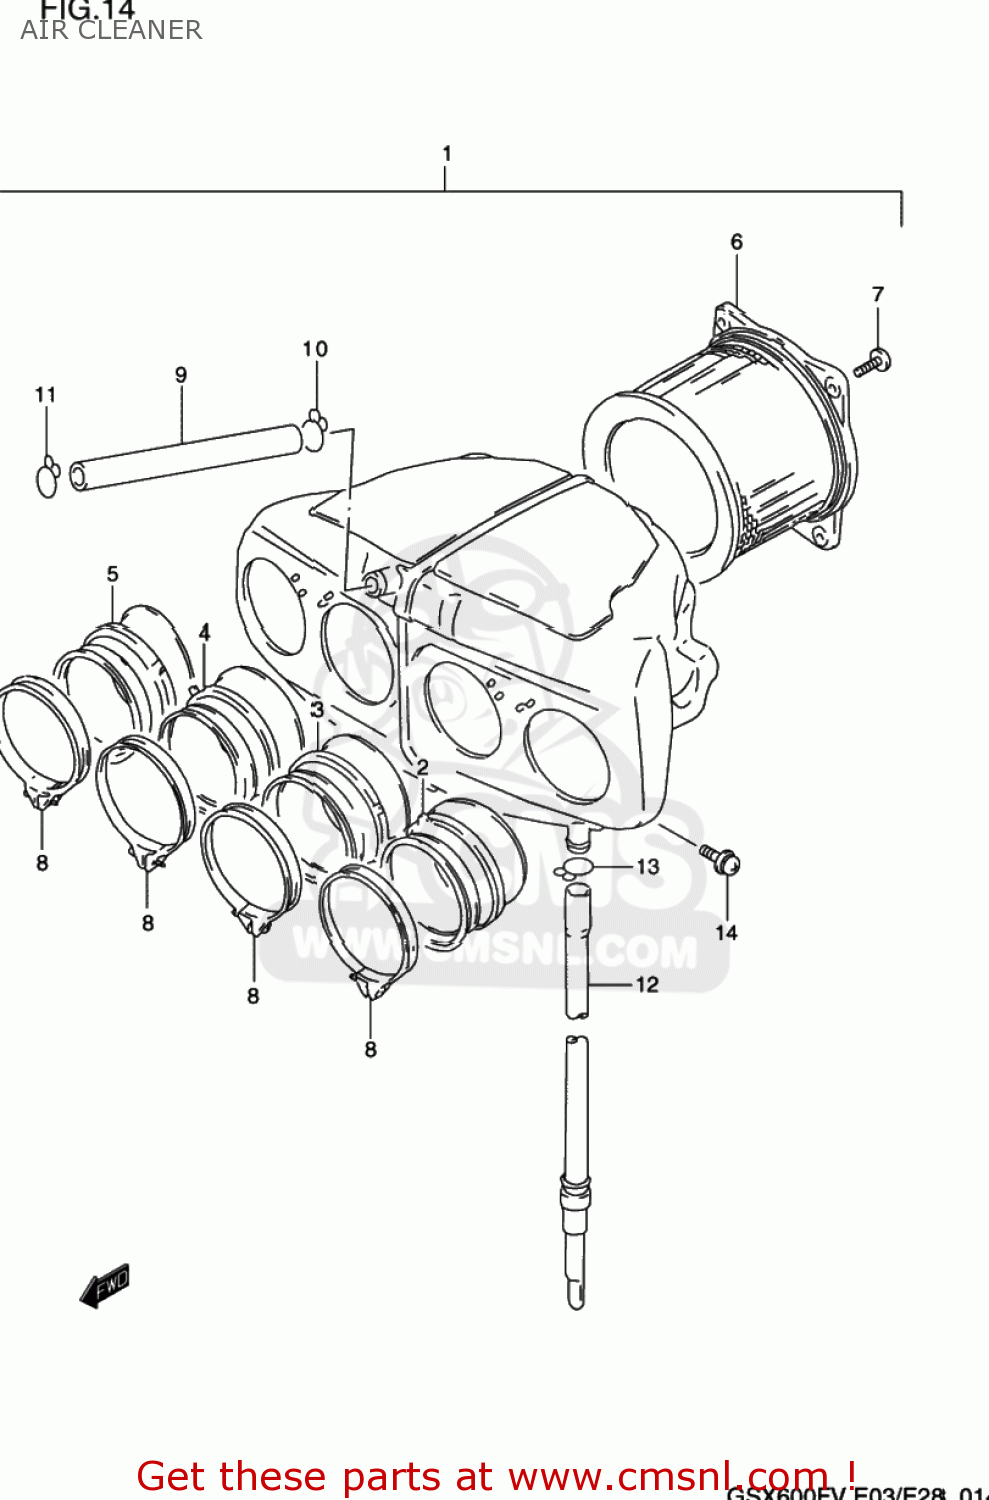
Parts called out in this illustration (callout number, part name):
1	CLEANER ASSY,AIR
2	TUBE,OUTLET,L
3	TUBE,OUTLET ML
4	TUBE,OUTLET MR
5	TUBE,OUTLET,R
6	FILTER ASSY
7	SCREW 5X12
8	CLAMP
9	TUBE,BREATHER
10	CLIP
11	CLIP
12	TUBE,DRAIN
13	CLIP
14	SCREW
